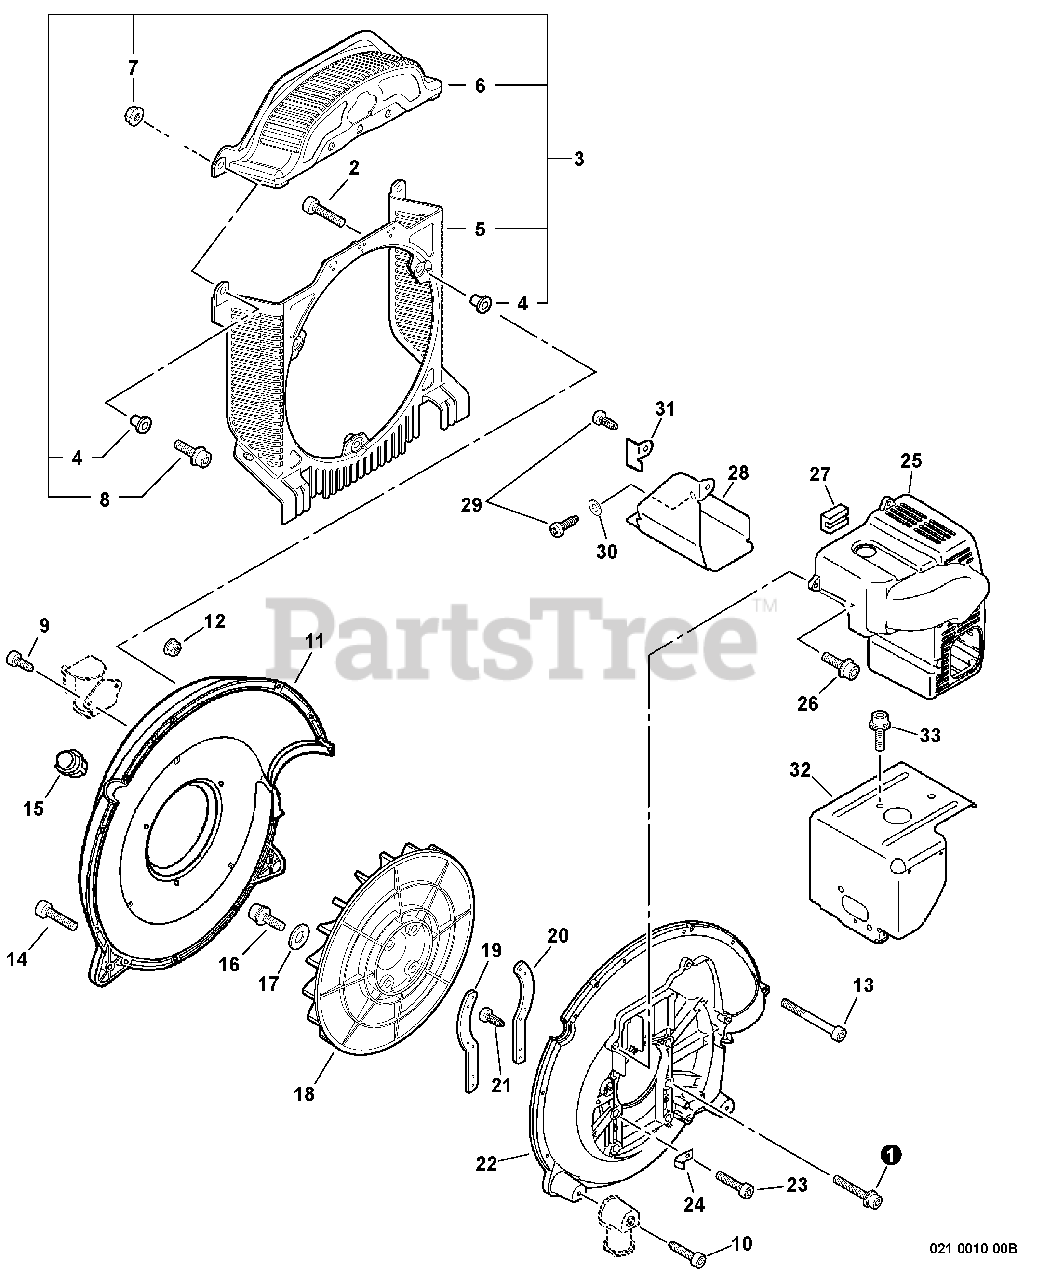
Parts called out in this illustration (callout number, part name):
1	SCREW - 6X35
2	SCREW - 5X20 -- TAPPING
3	DEBRIS GUARD KIT
5	GUARD, DEBRIS - LOWER
6	GUARD, DEBRIS - UPPER
7	LOCKNUT - 5
8	SCREW - 5X20
9	SCREW - 5X16
10	SCREW - 5X16
11	COVER, FAN - INNER
12	NUT - 5 -- FLANGE
13	SCREW - 5X60
14	SCREW - 5X20 -- TAPPING
16	SCREW - 6X35
17	WASHER - 6
19	PLATE - LEFT
20	PLATE - RIGHT
21	SCREW - 5X14
22	COVER, FAN - OUTER
23	SCREW - 5X16
25	COVER, ENGINE
26	SCREW - 5X20 -- TAPPING
27	CUSHION
28	SHIELD, EXHAUST
29	SCREW - 5X10
30	WASHER - 5
31	BRACKET, SHIELD
32	SHIELD, CYLINDER - INTAKE
33	SCREW - 6X35
